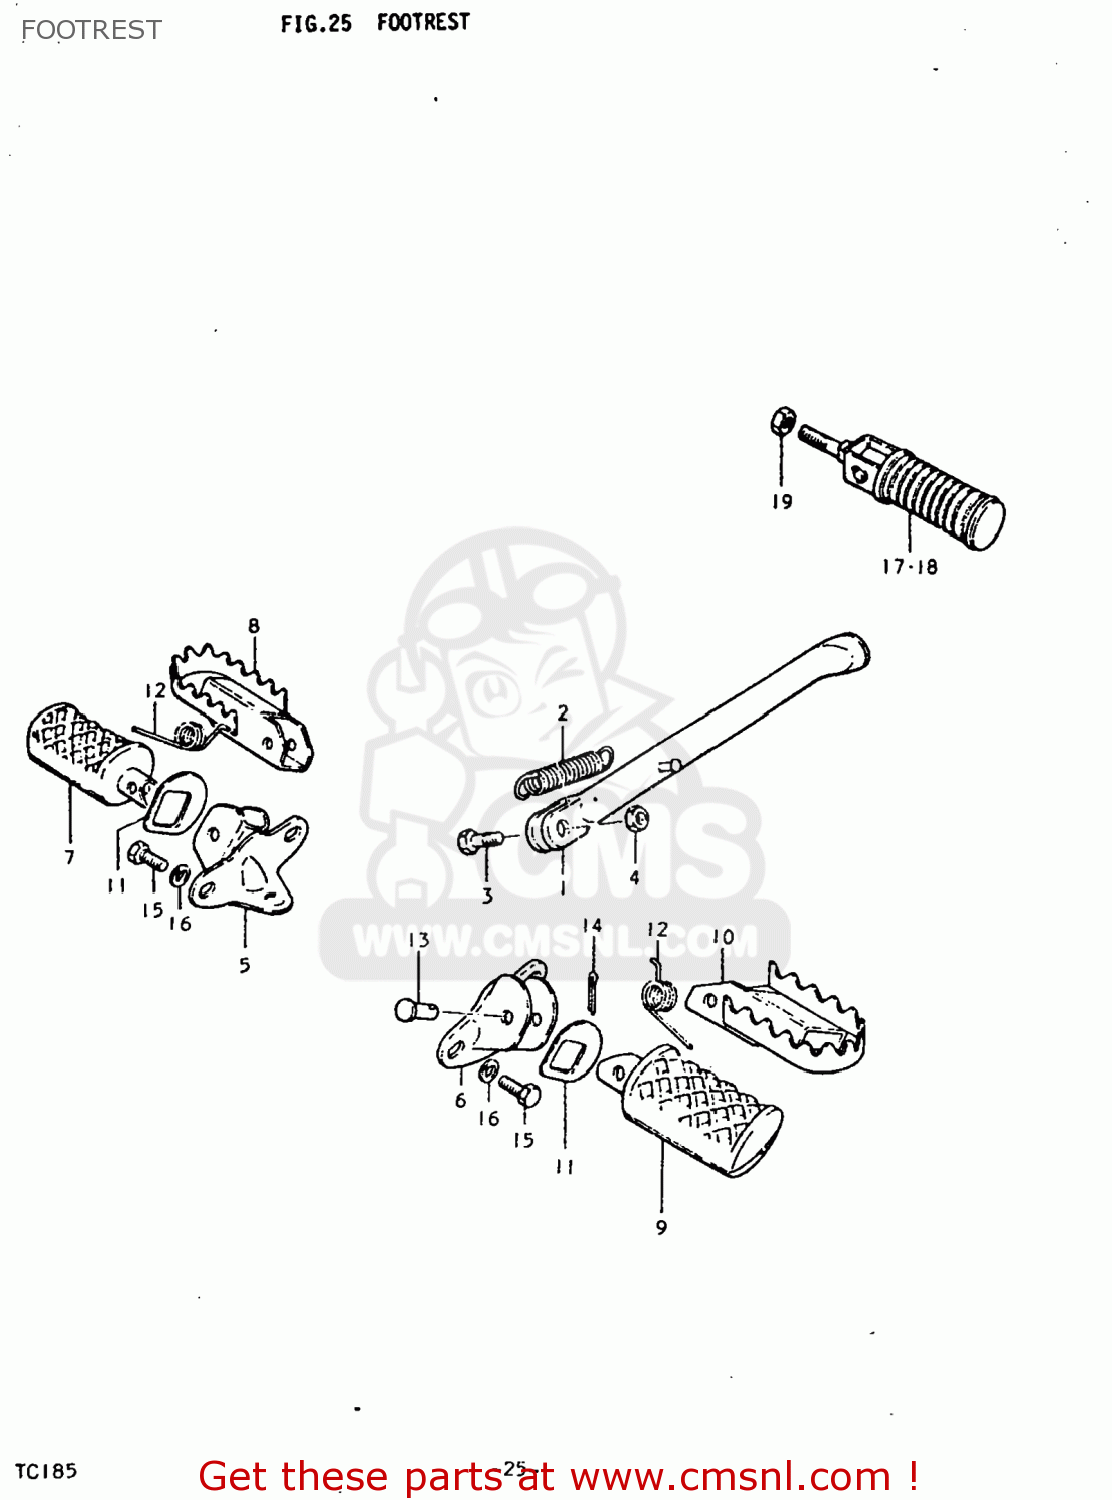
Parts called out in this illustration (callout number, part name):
1	STAND,SIDE
2	SPRING
3	BOLT(10X30)
4	NUT
5	BAR,FRONT FOOTREST
6	HOLDER,FRONT FOOTREST
7	RUBBER,FOOTREST,RIGHT
8	RUBBER,FOOTREST,RIGHT
9	RUBBER,FOOTREST,LEFT
10	RUBBER,FOOTREST,LEFT
11	WASHER
12	SPRING
13	PIN
14	PIN 20X20
15	BOLT
16	LOCK WASHER
17	FOOTREST ASSEMBLY,REAR
18	FOOTREST ASSY,PILLION
19	NUT
